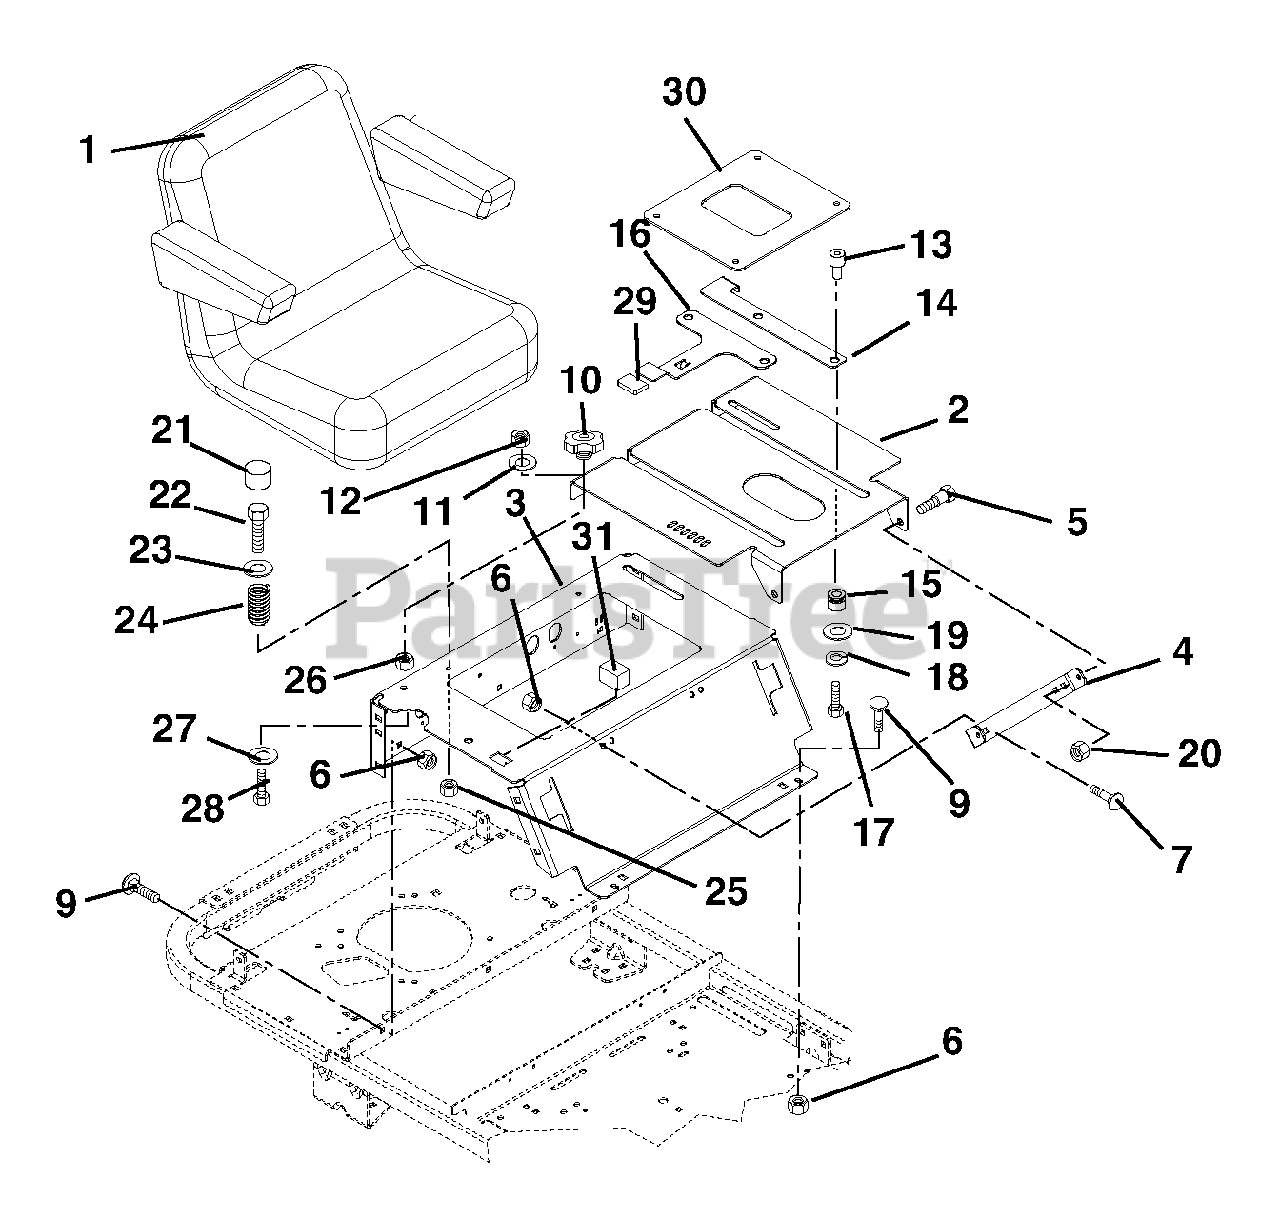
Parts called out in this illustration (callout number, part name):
1	Seat with Arm
2	Seat Plate
3	Seat Support
4	Bracket, Seat Plate
5	Bolt, Shoulder .375-16 x .135
6	Nut .38-16 Flange Nyloc
7	Bolt, Round Head Square Neck .38-16 x 1.00 Grade 5
8	Hour Meter, Quartz
9	Bolt, Round Head Square Neck .38-16 x 1.00 Grade 5
10	Knob, Clamping .312-18 Nyloc
11	Washer-Flat-Steel .328 x 1.00 x .094
12	Nut, Locking Nylon .312-18
13	Spacer, Seat Top
14	Seat Stop
15	Spacer, Seat Bottom
16	Lever, Seat Adjustment
17	Bolt-Hex .31-18 x 2.25 Grade 5
18	Washer-Locking .31 x .078 Regular
19	Washer, Flat Steel .312 x .734 x .065
20	Nut, Locking Top Flange .38-16
22	Bolt-Hex .31-18 x 1.00 Grade 5
23	Washer-Flat-Steel .344 x .688 x .065
24	Spring, Compression 2.9 x 2.02 O.D.
25	Nut 5/16-18 Flange Nyloc
26	Nut-Spin Lock-Flange .312-18
27	Washer-Flat-Steel .505 x 1.00 x .062
28	Bolt-Round Head Square Neck .31-18 x 3.50 Grade 5
30	Seat Support Plate
31	Plug, Headlight Switch
